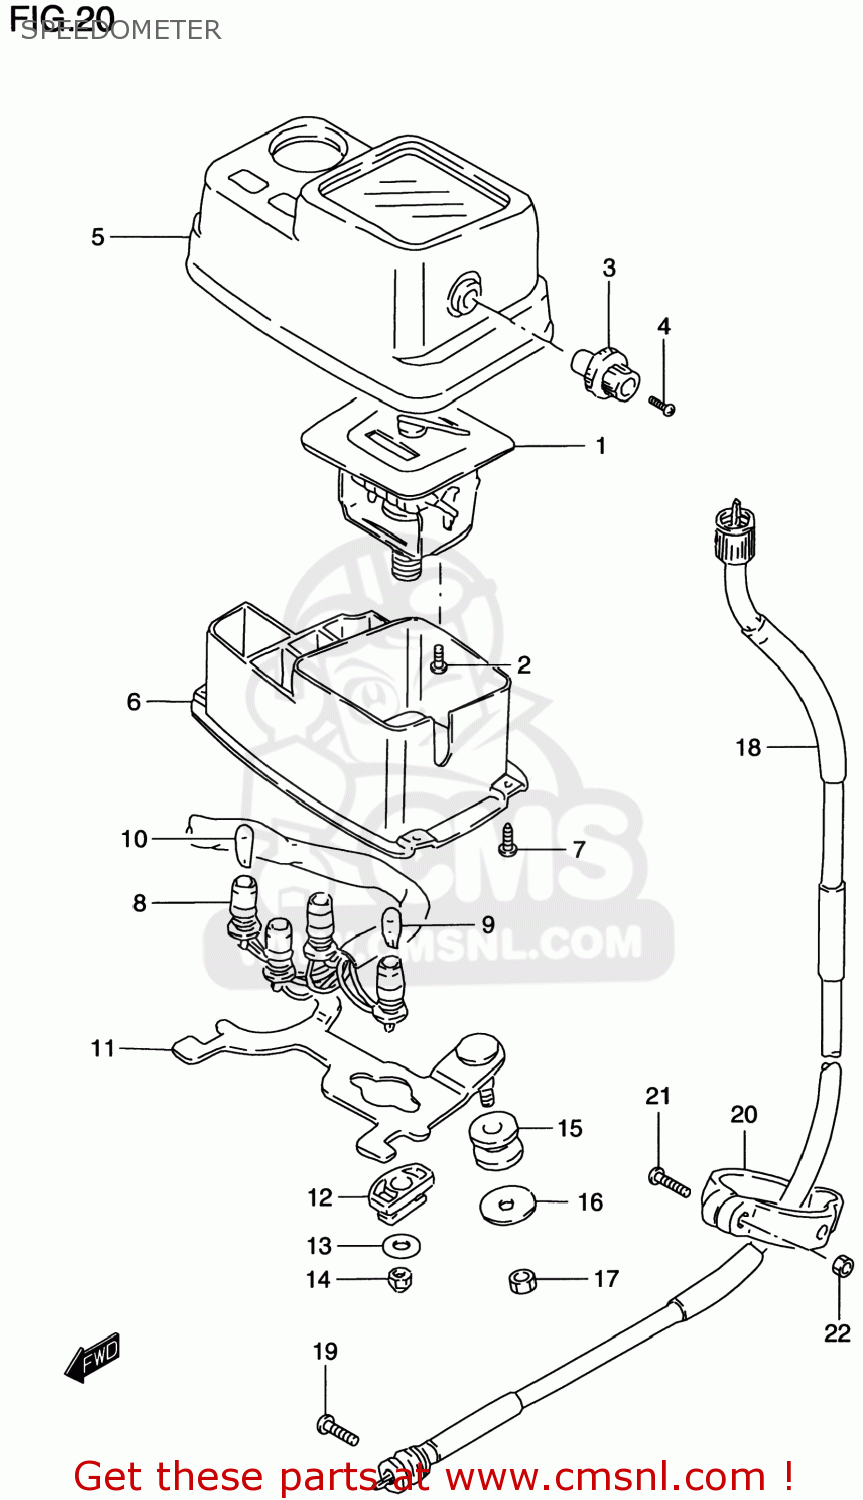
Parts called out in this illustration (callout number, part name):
1	SPEEDOMETER
2	SCREW
3	KNOB,TRIP
4	SCREW(2X6)
5	HOOD,METER
6	CASE,METER
7	SCREW
8	SOCKET ASSY
9	BULB(12V3.4W,T10)
10	BULB(12V1.7W,T10,WB121)
11	BRACKET,METER
12	CUSHION
13	WASHER(5.5X16X1.2)
14	NUT
15	CUSHION
16	WASHER(6.5X18X1.6)
17	NUT 6MM
18	CABLE ASSY,SPEEDOMETER
19	SCREW
20	CLAMP,SPEEDOMETER CABLE
21	SCREW
22	NUT
